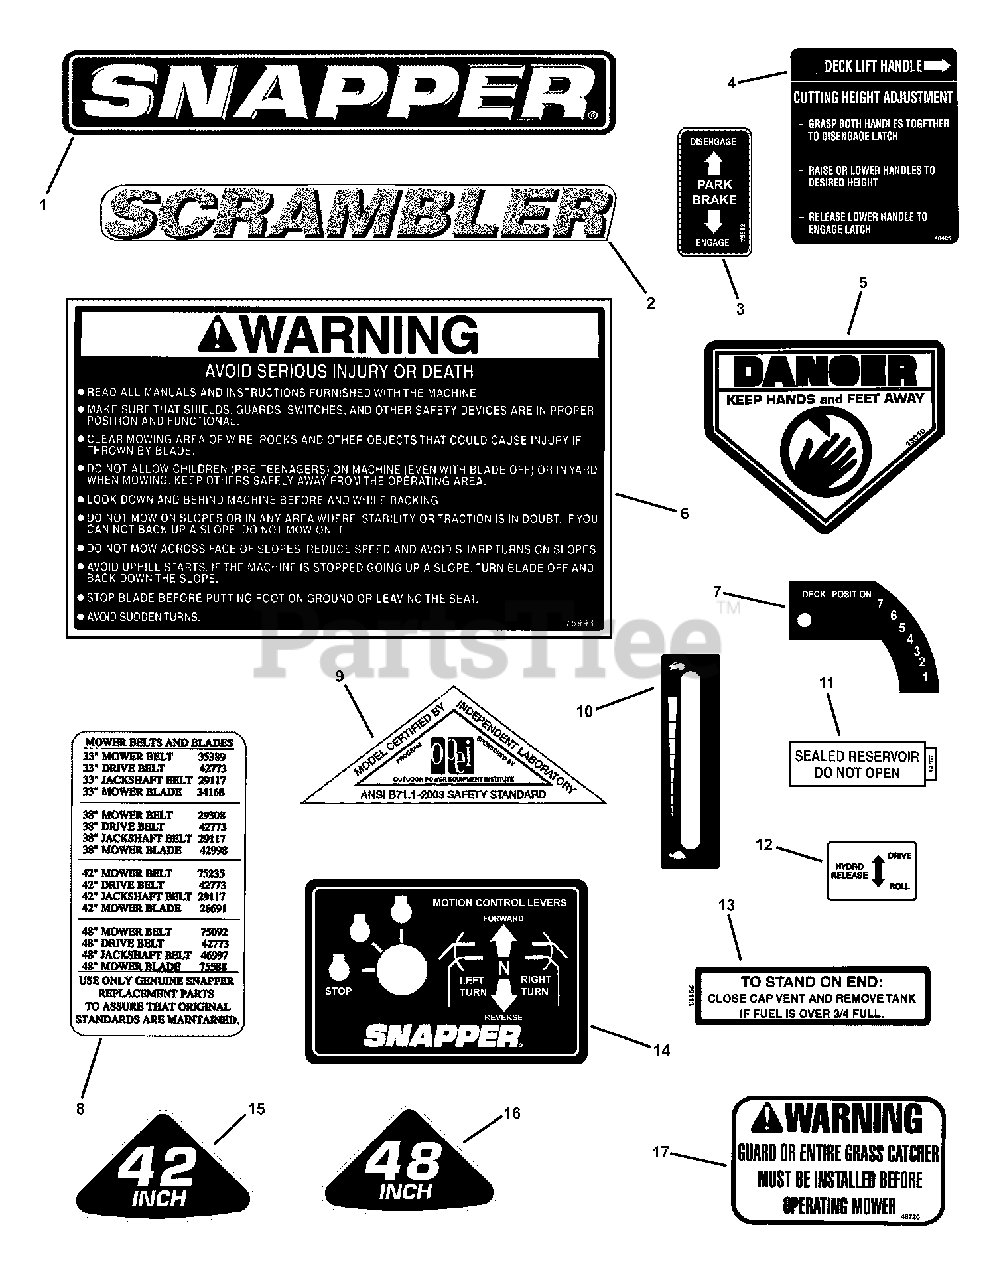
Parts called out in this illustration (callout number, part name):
1	DECAL, SNAPPER
2	DECAL, SCRAMBLER
3	DECAL, Park Brake
4	DECAL, Deck Height
5	DECAL, Danger, Cut Finger
6	DECAL, Warning, Read Manuals & Instructions
7	DECAL, Deck Position
8	DECAL, Service Parts, HOZ Domestic
9	DECAL, OPEI Walk/Ride
10	DECAL, Throttle/Choke Control
11	DECAL, Hydro Reservoir
12	DECAL, Hydro Release
13	DECAL, Caution, Fuel (English)
14	DECAL, Ignition Switch, Twin Stick
15	DECAL, 42" Deck
16	DECAL, 48" Deck
17	DECAL, Chute/Deflector
